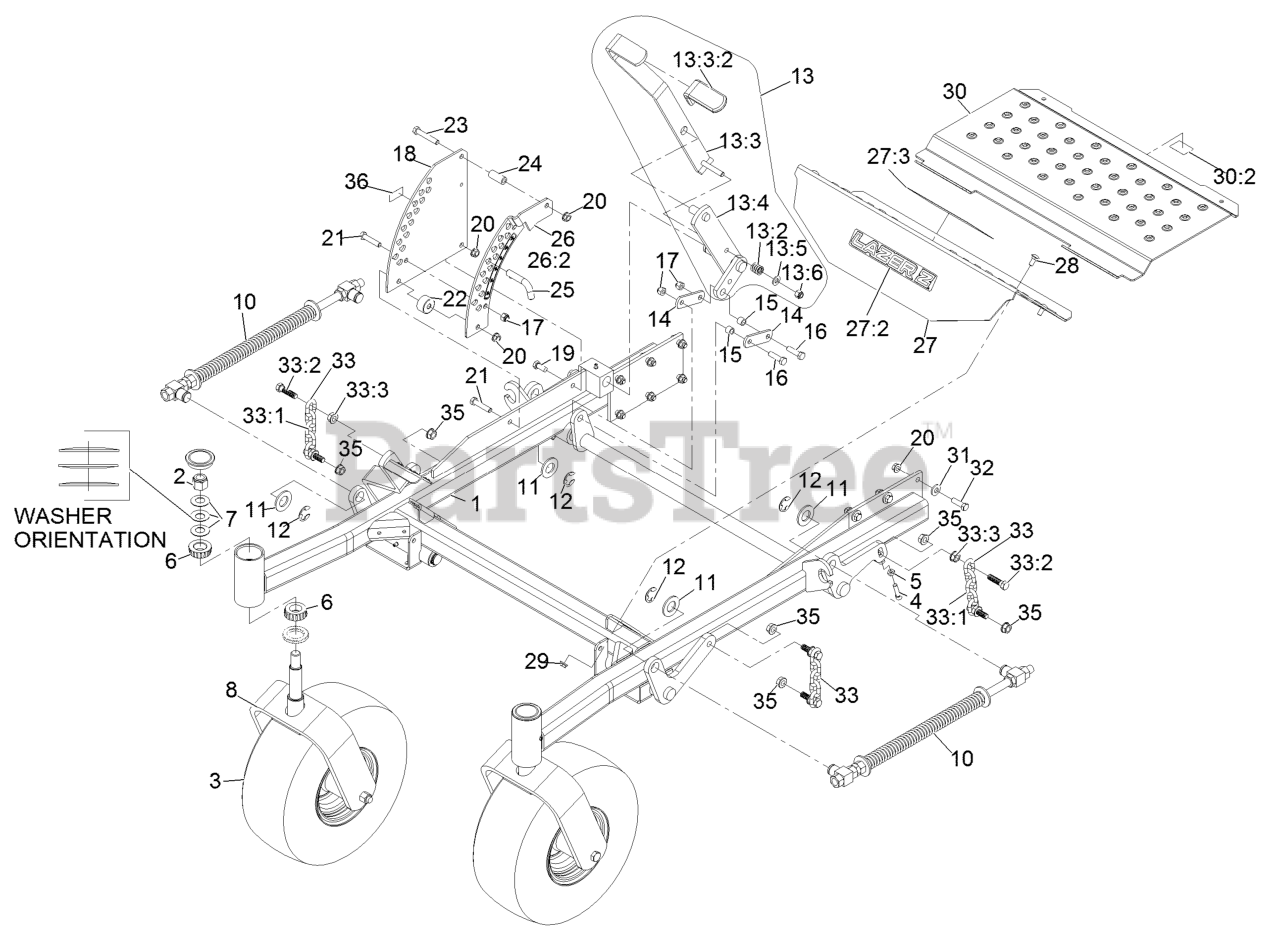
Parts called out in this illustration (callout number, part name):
1	ASM-FRT FRM 605
2	NUT-LOCK, NI
3	WHEEL & TIRE ASM
4	SCREW-HSH
5	NUT-JAM
6	Cone-Bearing Tapered Roller
7	WASHER-BELLVILLE
10	ASM,FRONT FRAME SPRING
11	WASHER-FLAT
12	RING-RETAINING, EXT
13	ASM,Deck Lift Handle
13:2	SPRING-COMPRESSION
13:3	LIFT LEVER/GRIP ASM
13:3:2	GRIP-LEVER, LIFT
13:4	WLD,ARM DECK LIFT
13:5	WASHER-FLAT
13:6	NUT-LOCK, NI
14	ARM-LIFT, DECK
15	BUSHING
16	SCREW-HH
17	NUT-LOCK, NI
18	PLATE-DECK LIFT NOTCHED O
19	SCREW-HH
20	NUT-HHF, WHIZ
21	SCREW-HH
22	Stop, Deck Height
23	SCREW-HH
24	BUSHING-LEVER, LIFT
25	PIN-HOC
26	PLATE-LIFT, DECK W/DECAL
26:2	DECAL-HEIGHT OF CUT
27	ASM, FLOORPAN FRONT W/DEC
27:2	DECAL, LAZER MODEL
27:3	DECAL-DANGER
28	BOLT-CARR
30	ASM, FLOORPAN LIFTOUT W/D
30:2	Decal-Guard
31	WASHER-BELLEVILLE
32	SCREW-HH
33	DECK CHAIN ASM
33:1	CHAIN-LIFT, DECK
33:2	SCREW-HH
36	Decal-Patent Ttco.Com
